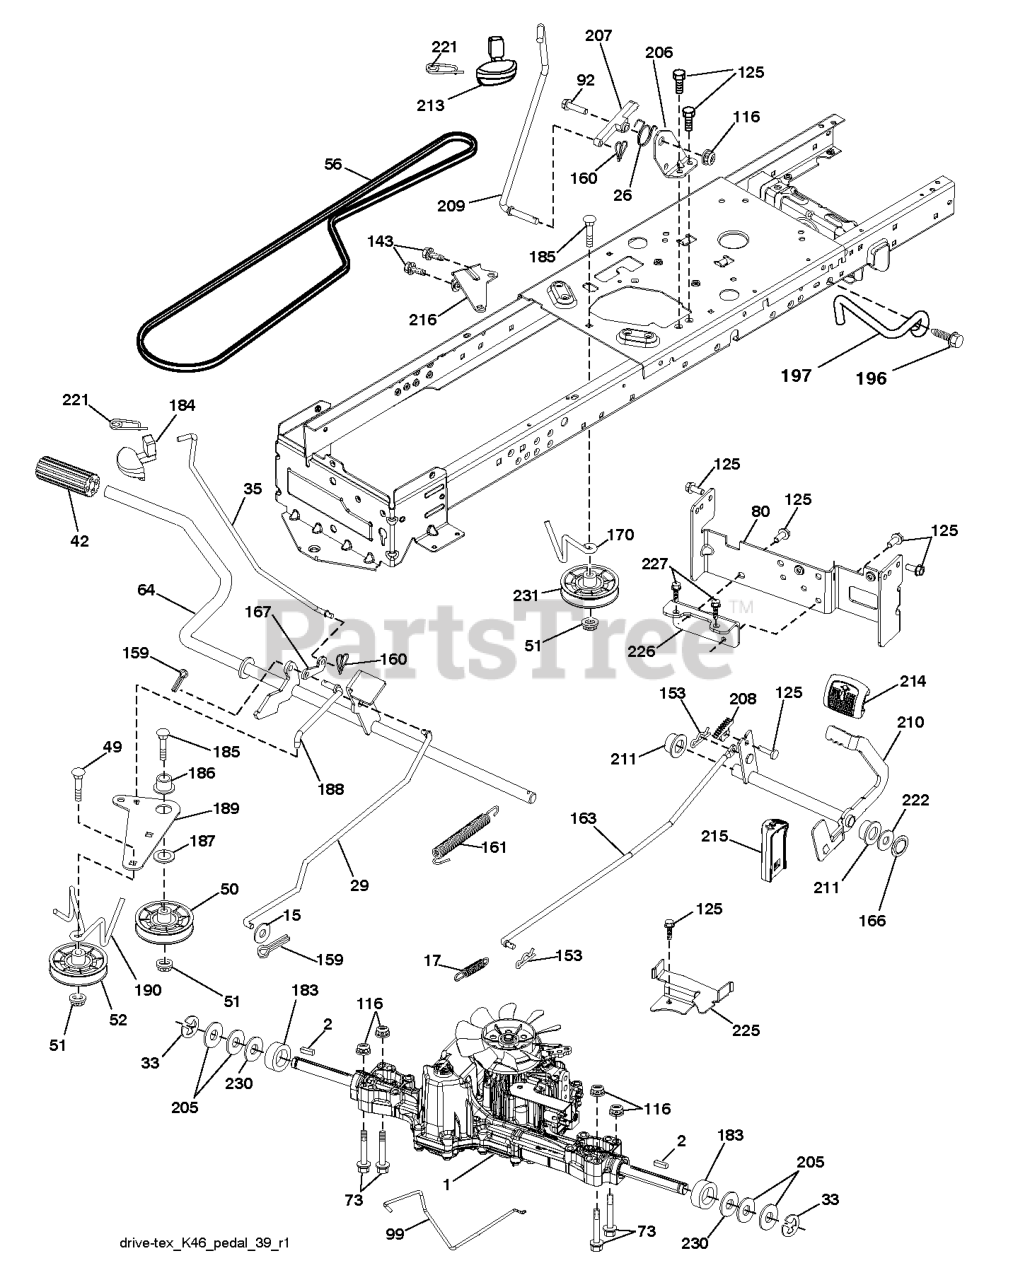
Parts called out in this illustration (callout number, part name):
2	SQUARE KEY
15	WASHER
17	SPRING.BRAKE.K46.GREEN
26	SPRING.RETURN.CRUISE
29	ROD.BRAKE.K46
35	ROD.BRAKE.PARTK.HUSQ.TEX
42	PEDAL COVER T
50	IDLER.FLAT.910.OFFSET
51	NUT LOCK FLG 3/8-16 UNC
52	IDLER.V-GROOVE.910.OFFSET
56	V-BELT.MOWER.92.40.42/K46
64	SHAFT.ASM.PEDAL.BRK.CNTR
73	BOLT
80	STRAP.TORQUE.K46.K57R.TT
92	BOLT
99	ROD.SPRING.BYPASS.K46.LT.Z
116	NUT LOCK HEX FLANGE 5/16-18
125	SCREW
143	SCREW LT
153	RETAINER M
159	COTTER PIN
160	RETAINER CLIP
161	SPRING, RETURN LT
163	ROD.CONTROL.K57R.K46
166	NUT.PUSH.625
167	LATCH.BRAKE.SPRING
170	KEEPER.CENTER SPAN.1.688
183	SPACER AXLE
184	RB HANDLE.PARKG.BRK.HUS/PRED
186	SPACER.RETAINER
187	WASHER 12/32X2X10GA
188	RP.LINK.CLUTCH.GROUND.DRIVE
189	BELLCRANK.GROUND.DRIVE.TEX.
190	KEEPER.BELLCRANK.DRIVE
196	SCREW 3/8-16X1
197	LINK.CLUTCH.ANIT-ROTAT
206	BRKT.MOUNT.LATCH.CRUIS
207	LATCH.CONTROL.CRUISE
208	GEAR.SECTOR.CONTROL.CR
209	ROD.CONTROL.CRUISE.GT.
210	ROCKER.ASM.PEDAL.CONTR
211	BEARING.NYLON
213	KNOB.CONTROL.CRUSIE.HU
214	PEDAL.FORWARD.PAD.TEX
215	PEDAL.REVERSE.TEX.GT.4
216	BRACKET.PULLEY.IDLER.W/TEX
221	RETAINER.SPRING.CLIP.H
222	WASHER 21/32 X 1-1/4 X 10 GA.
225	KEEPER.BELT.TRANSAXLE.K46
226	BRACKET.MOUNT.TORQUE.K46.TLT
227	SCREW.THDROL.5/16-18X3/4.TTY
230	WASHER.HARDENED
231	IDLER.V-GROOVE.1.688.OFFSET
